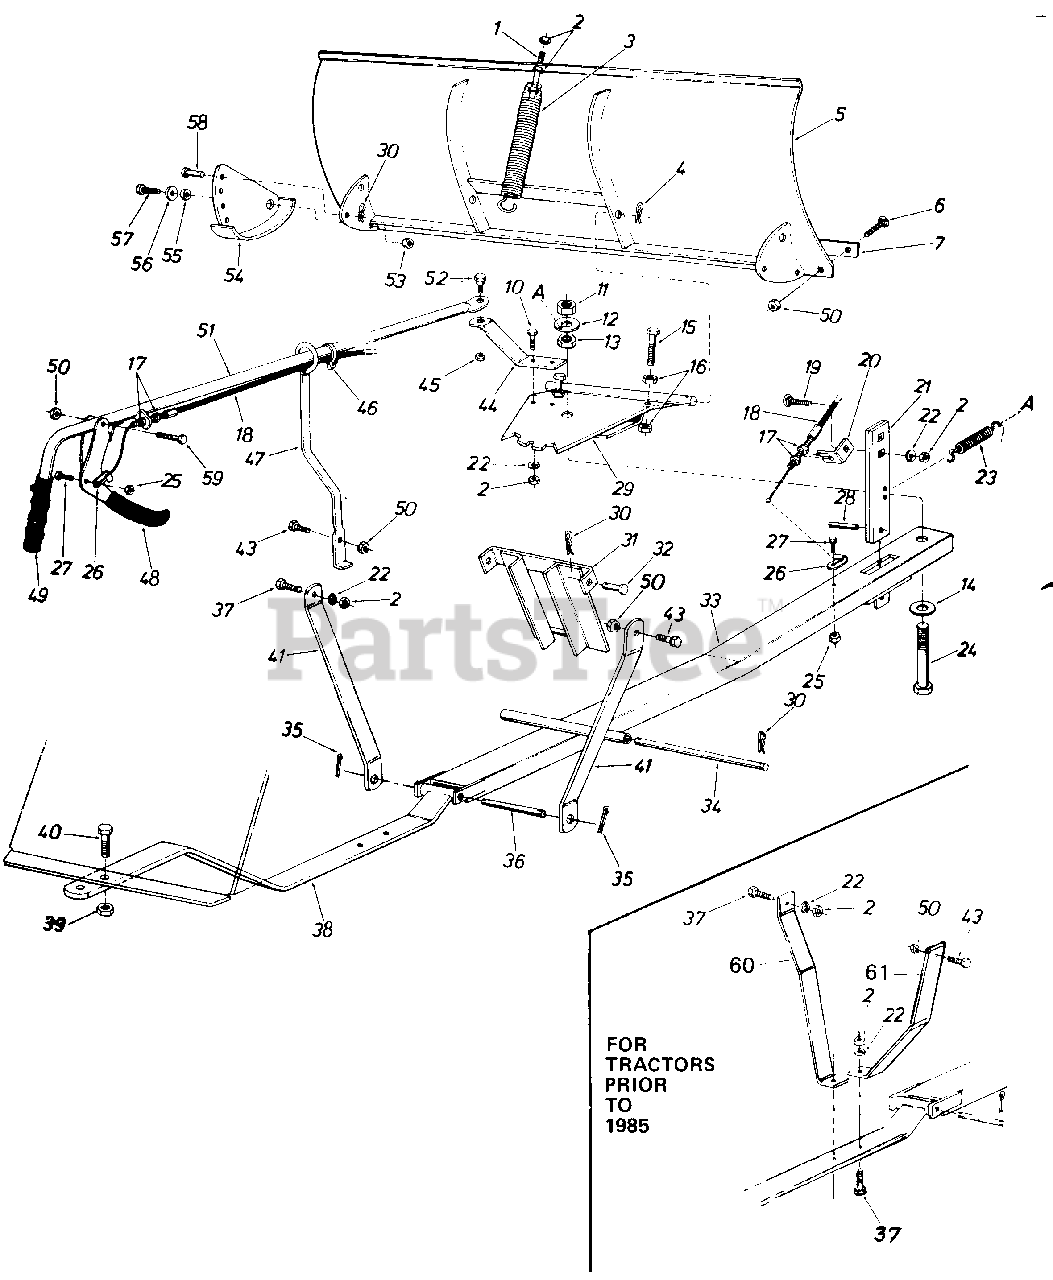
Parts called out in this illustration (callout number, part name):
1	Hex Scr. 3/8-16 x 4.50" Lg.*
2	Hex Nut 3/8-1 Thd.*
3	Blade Adjustment Spring
4	Hair Pin Cotter 5/32" Dia.
5	48" Blade Ass'y.
6	Carriage Bolt 5/16-18 x.75" Lg.*
7	Wear Plate 48"
10	Hex Scr. 3/8-16 x 1.00" Lg.*
11	Hex L.-Nut 3/4-10 Thd.
12	Fl.-Wash. .810" I.D. x 2.00" O.D.
13	Hex Jam Nut 3/4-10 Thd.*
14	Fl.-Wash..810" I.D. x 2.00" O.D.
15	Hex Scr. 1/2-13 x 2.00" Lg.*
16	Hex Nut 1/2-13 Thd.*
17	Hex Jam Nut 5/16-24 Thd.*
18	Control Cable Ass'y.
19	Carriage Bolt 3/8-16 x 1.25" Lg.*
20	Cable Guide Bracket
21	Angle- Lock Bar
22	L.-Wash. 3/8" Scr.*
23	Angle Lock Spring
24	Hex Scr. 3/4-10 x 4.00" Lg.
25	Hex L.-Nut 1/4-20 Thd.
26	Clevis Lanyard Fitting
27	Hex Scr. 1/4-20x .75" Lg.*
28	Spring Pin Spirol 1/4" Dia. x 1.00" Lg.
29	Pivot Plate Ass'y.
30	Hair Pin Cotter 3/32" Dia.
31	Guide Bracket Ass'y.
32	Clevis Pin 1/2" Dia. x 1.00" Lg.
33	Push Bar Ass'y.
34	Lift Shaft
35	Cotter Pin 5/32" Dia. x 1.00" Lg.*
36	Pivot Pin
37	Hex Scr. 3/8-16 x 1.25" Lg.*
38	Hanger Bracket Ass'y.
39	Hex L.-Nut 5/8-11 Thd.
40	Hex Scr. 5/8-11 x 1. 50" Lg.*
41	Hanger Link
43	Hex 5/16-18 x 1.00" Lg.*
44	Blade Pivot Bracket
45	Hex L.-Nut 3/8-16 Thd.
46	Nylon Cable Tie
47	Tube Guide Ass'y.
48	Clutch Grip Ass'y.
49	Grip - 3/4" Handle
50	Hex L-Nut 5/16-18 Thd.
51	Tube Handle Ass'y.
52	Shld. Scr. - Special 3/8-16 Thd.
53	Hex L.-Nut 3/8-16 Thd.
54	Skid Assembly
55	Spacer
56	Fl.-Wash..385" I.D. x 1.00" O.D.
57	Hex Scr. 3/8-16 x .75" Lg.*
58	ClevisPin5/16" Dia. x.75" Lg.
59	Hex Scr. 5/16-18 x 1.50' Lg.
60	Mounting Brkt.-L.H.
61	Mounting Brkt.-R.H.
